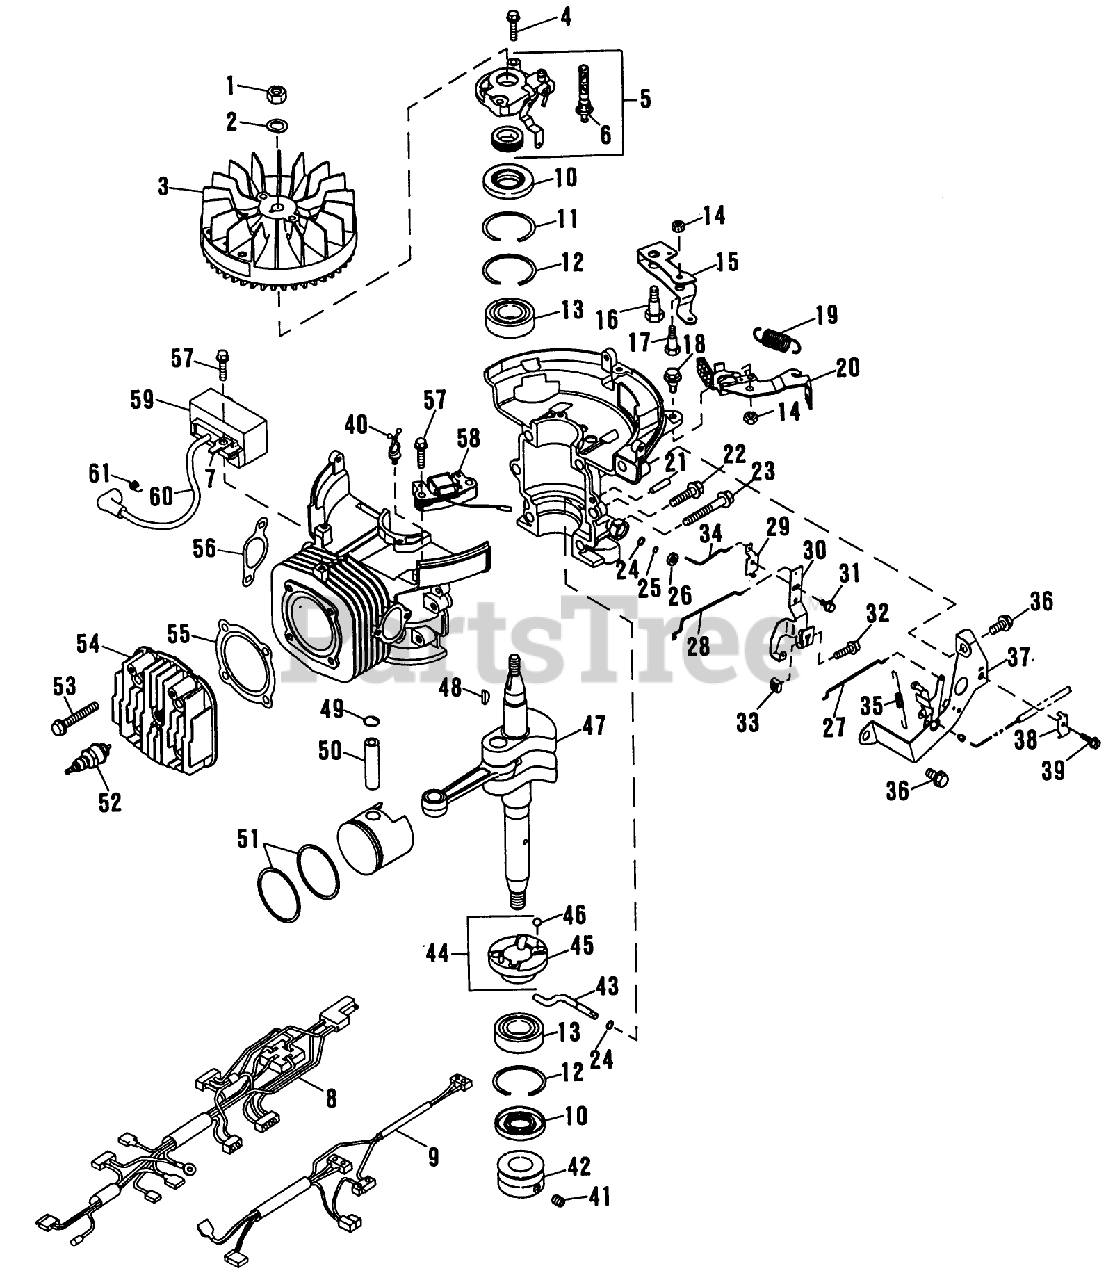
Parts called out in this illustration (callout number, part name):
1	NUT
3	FLYWHEEL AY SM
4	SCREW
10	SEAL - OIL SM
11	RING-RETAINER SM
13	BEARING-BALL SM
14	LOCKNUT E
15	ACT.BRAKE LVR. SM
16	SCREW-SHOULDER
19	SPRING-BRAKE
22	SCREW-H.W.HD. F
23	SCREW-HEX W.H. SM
25	RING-RETAINING
26	SEAL - OIL SM
28	ROD-THROTTLE SM
31	SCREW
37	GOVNR BRKT SM
40	WIRE TIE SM
42	PULLEY-ENGINE
48	KEY
51	RING SET S
53	SCREW
54	CYLINDER HEAD SM
56	GASKET - EXH SM
57	SCREW
58	ALTERNATOR ASM
60	HI-TENS.LEAD
